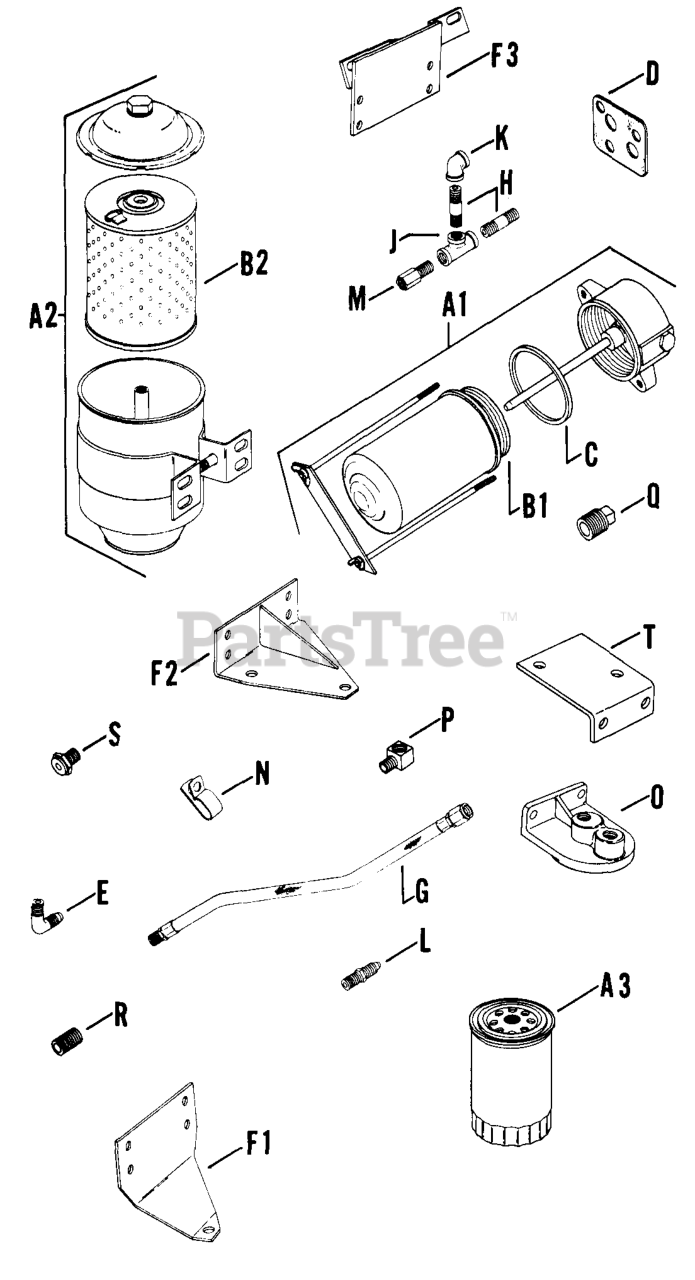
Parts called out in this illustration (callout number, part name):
A3	FILTER, OIL
G	Line, oil 12
L	CONNECTOR
M	Restriction
P	ELBOW, STREET 1/8 NPTF BRASS USE 25 054 13-S
